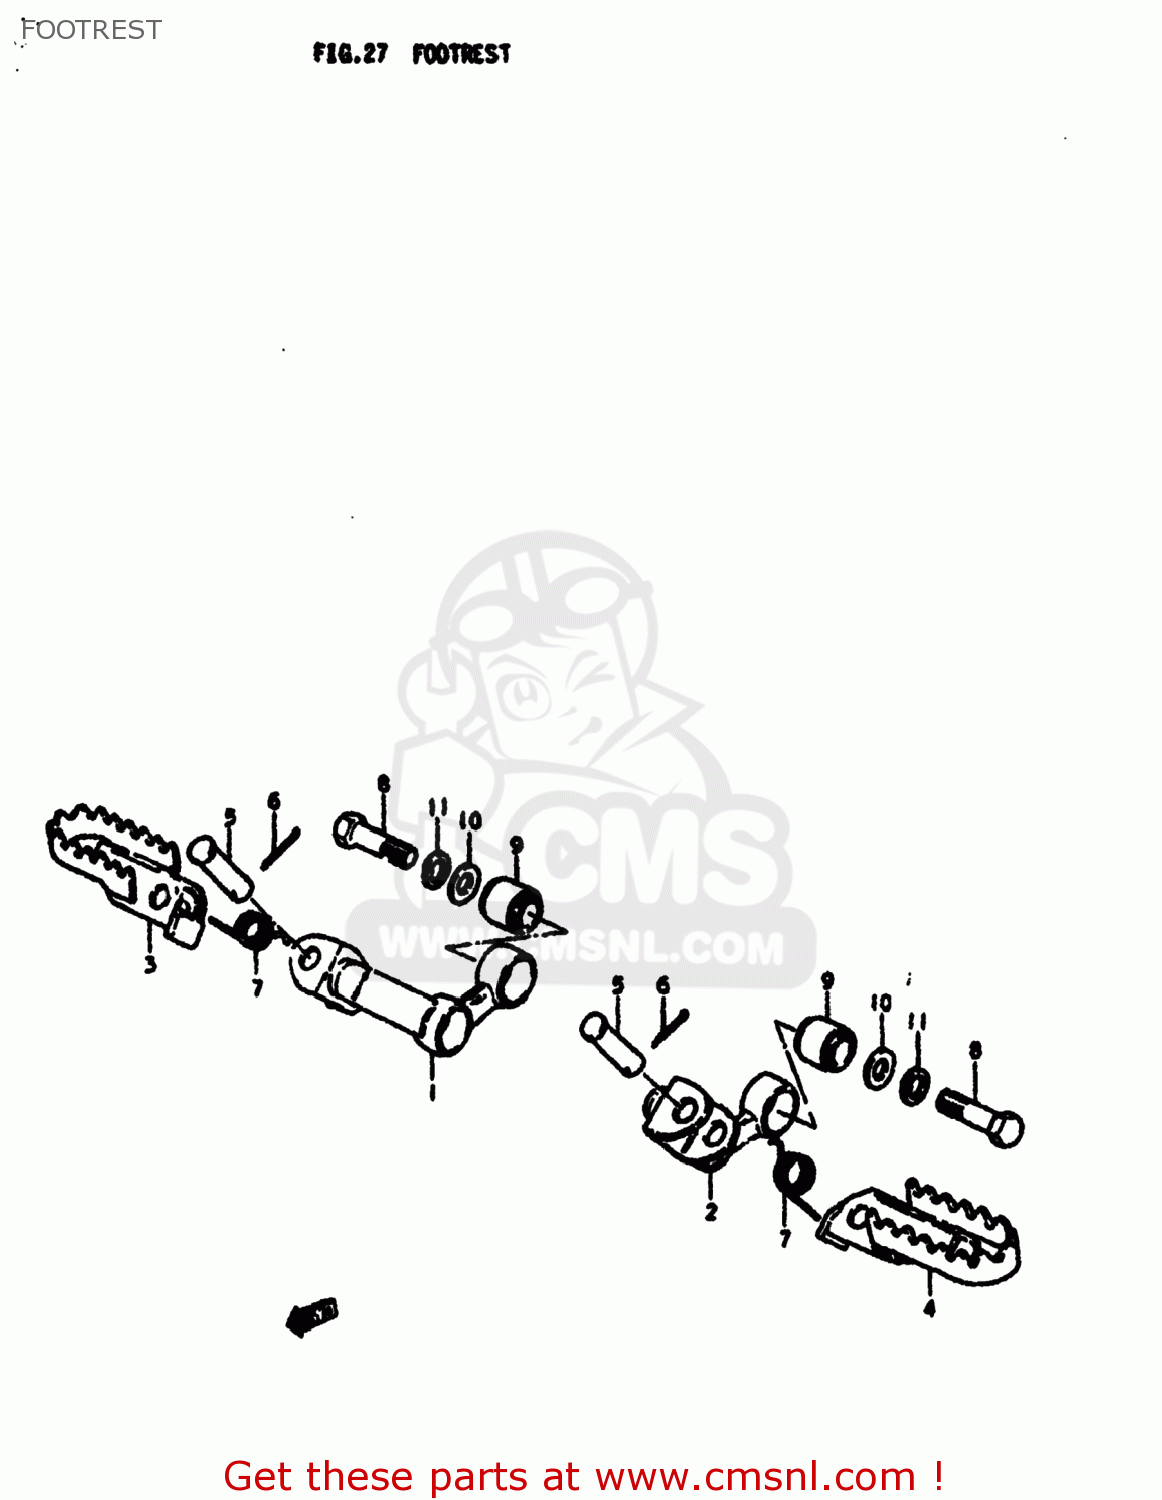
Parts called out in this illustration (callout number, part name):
1	BAR,FRONT FOOTREST
2	BRACKET COMP,FRONT FOOTREST
3	FOOTREST,FR,R
4	FOOTREST,FR,L
5	PIN
6	PIN 20X20
7	SPRING
8	BOLT
9	BUSH
10	WASHER (10.1X21X2.3)
11	LOCK WASHER
